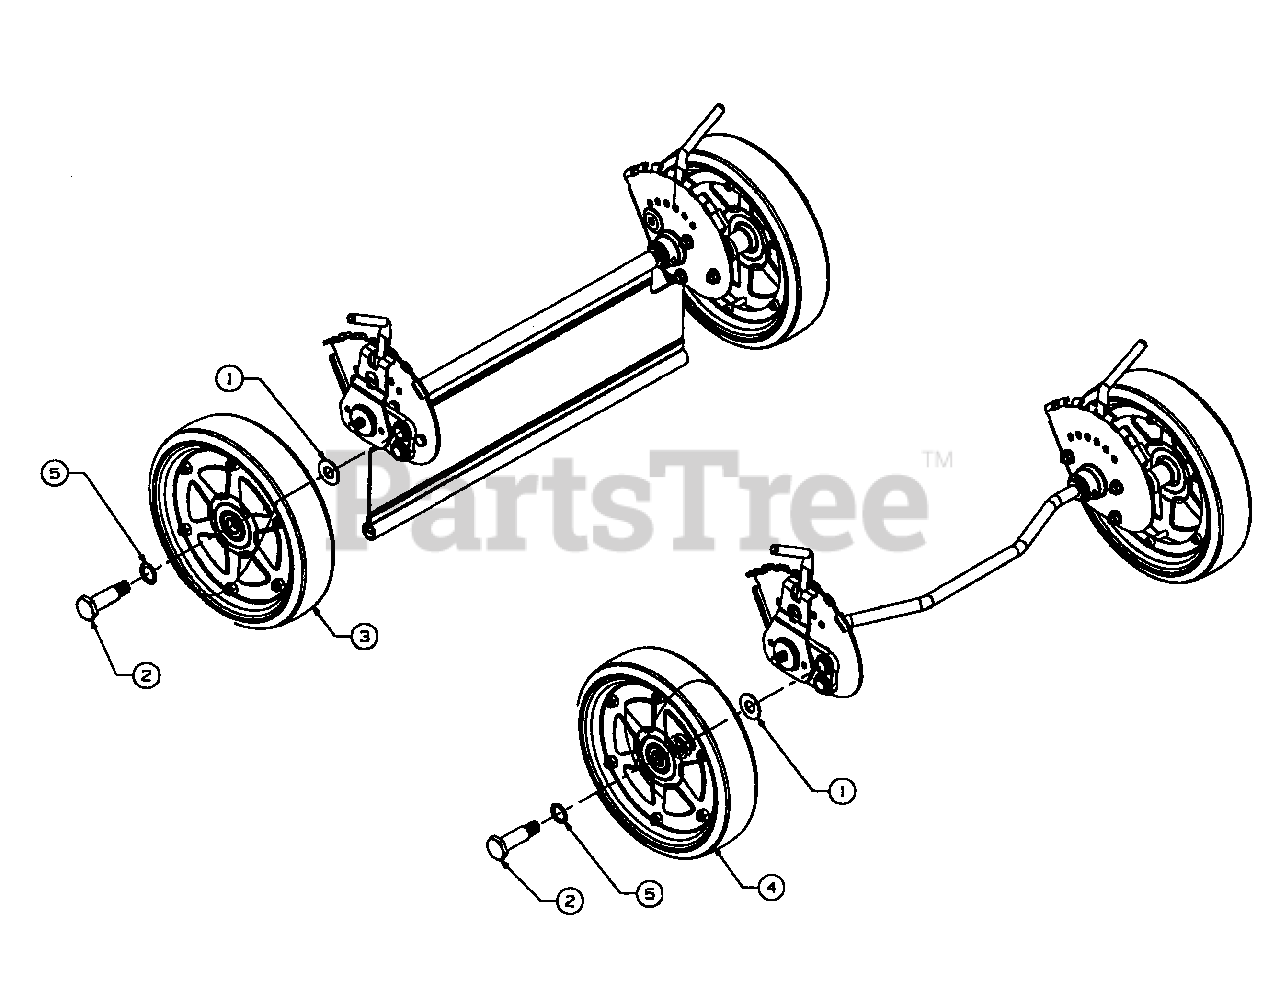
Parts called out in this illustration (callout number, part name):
1	WASHER: THRUST
2	BOLT:SHLDR:1/2-20 X 1.48
3	WHL:COMP: 9 X 2.125 W/GEAR (BIEGE)
4	WHL:COMP: 9 X 2.125 W/O, GEAR (BIEGE)
5	WASH: SHIM: .625 X .875 X .031
